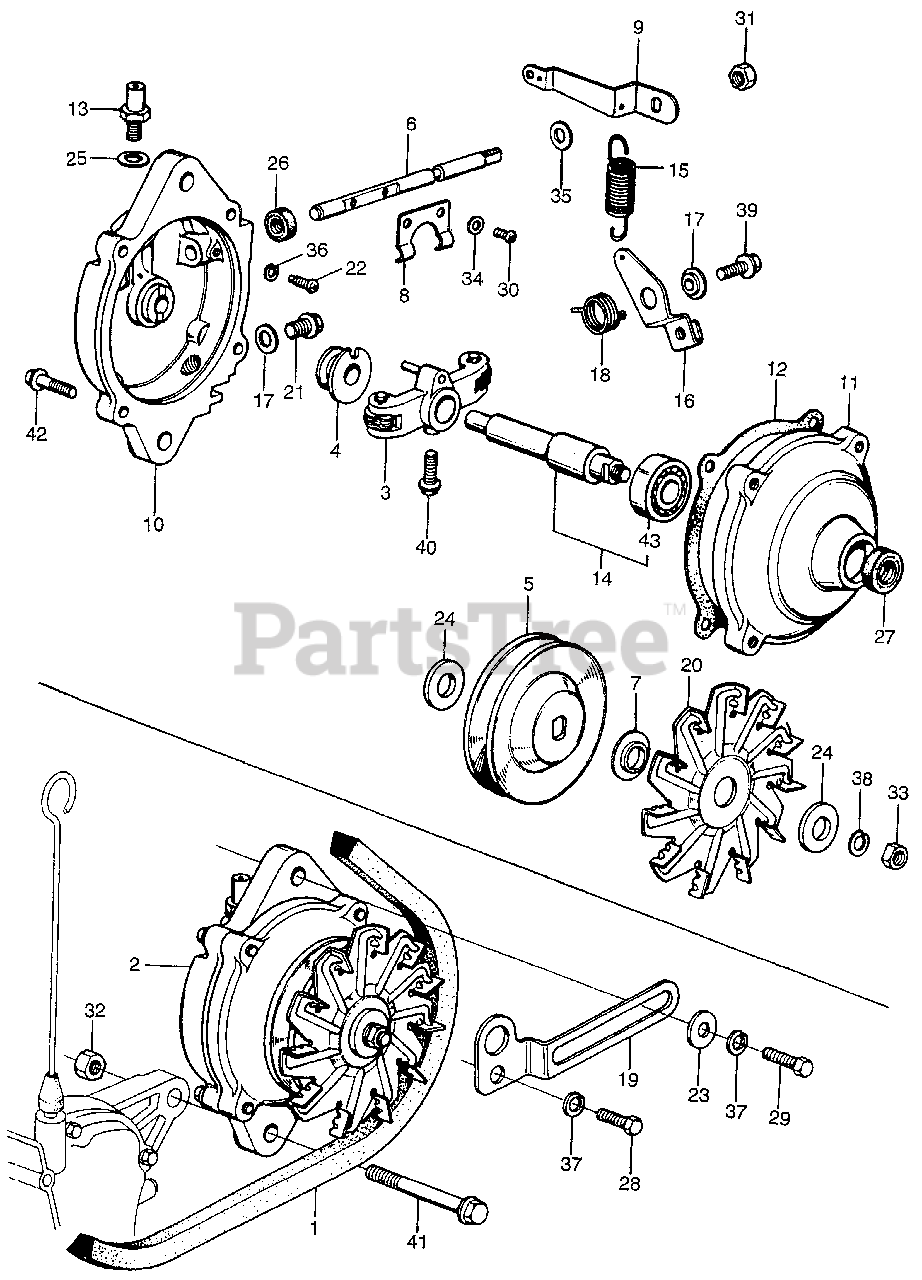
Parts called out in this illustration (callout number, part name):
1	BELT KIT (NOT AVAILABLE)
2	GOVERNOR ASSY. (NOT AVAILABLE)
3	WEIGHT, GOVERNOR
4	SLIDER, GOVERNOR (NOT AVAILABLE)
5	PULLEY KIT, GOVERNOR
6	SHAFT, GOVERNOR ARM
7	COLLAR, GOVERNOR FAN
8	ARM, GOVERNOR (NOT AVAILABLE)
9	LEVER, GOVERNOR (NOT AVAILABLE)
10	COVER, GOVERNOR (NOT AVAILABLE)
11	CASE, GOVERNOR
12	GASKET, GOVERNOR CASE
13	BODY, GOVERNOR BREATHER
14	SHAFT, GOVERNOR
15	SPRING, GOVERNOR (NOT AVAILABLE)
16	LEVER, THROTTLE
17	COLLAR, THROTTLE ARM (NOT AVAILABLE)
18	SPRING, RETURN (NOT AVAILABLE)
19	STAY, GENERATOR
20	FAN, ALTERNATOR
21	BOLT, PLUG (10MM)
22	SCREW, PAN SPECIAL (4X8)
23	WASHER (8MM) (NOT AVAILABLE)
24	WASHER (38X11X4)
25	WASHER (10MM)
26	OIL SEAL (8X18X5) (NOT AVAILABLE)
27	OIL SEAL (17X30X8)
28	BOLT, HEX. (8X20)
29	BOLT, HEX. (8X25)
29	BOLT, HEX. (8X28)
30	SCREW, PAN (4X8)
31	NUT, HEX. (6MM)
32	NUT, HEX. (10MM)
33	NUT, HEX. (10MM)
34	WASHER, PLAIN (4MM)
35	WASHER, PLAIN (6MM)
36	WASHER, SPRING (4MM)
37	WASHER, SPRING (8MM)
38	WASHER, SPRING (10MM)
39	BOLT, FLANGE (6X16)
40	BOLT, FLANGE (6X20)
41	BOLT, FLANGE (10X65)
42	BOLT, FLANGE (6X28)
43	BEARING, RADIAL BALL (6003)
